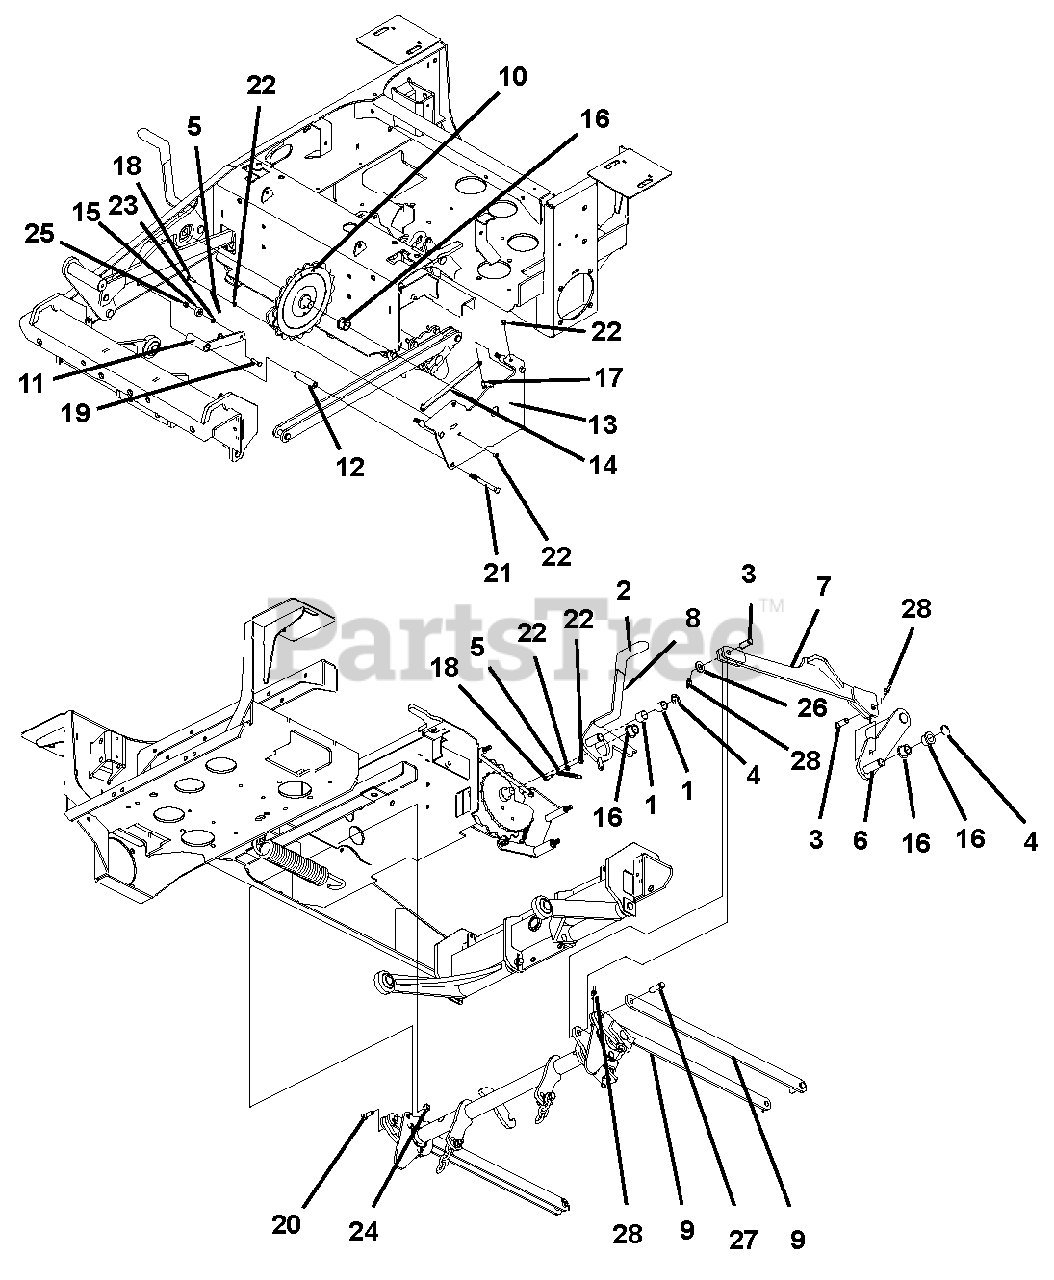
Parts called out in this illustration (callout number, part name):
1	Bearing, Sleeve .753 x .878 x .750
2	Grip, Rubber Lever
3	Pin, Clevis .500 x 1.25 x 1.02 Y
4	E-Ring, .750 x .050
5	Spring, EXT .375 x .055 x 2.25
6	Weldment, Foot Arm
7	Weldment, Foot Connector
8	Weldment, Transportation Lock
9	Plate, Connector Link
10	Assembly, Cam Control w/Decals S/O
11	Weldment, Arm
12	Tube, .625 x .120 x 2.53
13	Plate, HOC Indicator
14	Plate, Finger Guard
15	Bearing, Ball .250 x .688 x 313
16	Bushing, .750 x 1.00 x .750
17	Bolt, 1/4-20 x .500 HEX 5
18	Bolt, 1/4-20 x .750 HEX 5
19	Bolt, 1/4-20 x 1.00 HEX 5
20	Bolt, .38-16 x 1.00 HEX 5
21	Bolt, 3/8-16 x 3.50 HEX 5
22	Nut, 1/4-20 STD HEX
23	Washer, Flat, Steel M6 7 x 13 x 1.5
24	Nut, Locking, Flange .375-16
25	Nut, Locking, Nylon .250-20
26	Washer, Flat, Steel .531 x 1.06 x .095
27	Pin, Clevis .500 x 1.50 x 1.27
28	Ring, Rue .500 x .062 x 1.420
